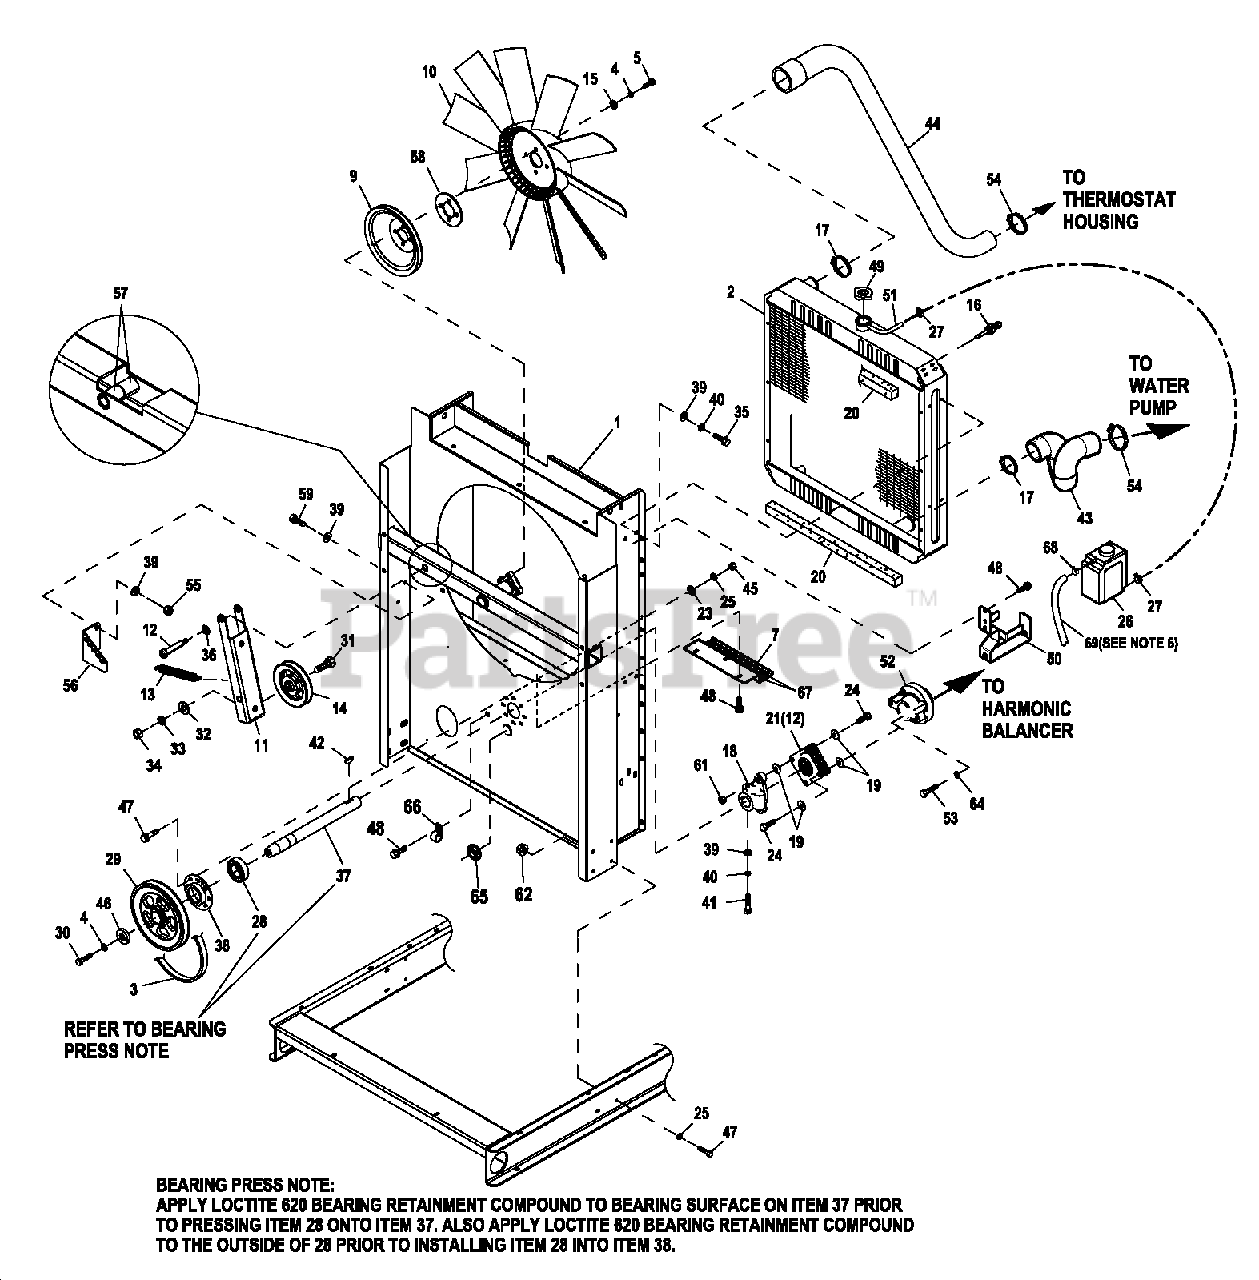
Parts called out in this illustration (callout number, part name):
1	WELDMENT RADIATOR SUPPORT C2
2	RADIATOR 598 X 568 X 19.CPL LH
3	V-BELT A51 (53INO.C)
4	WASHER LOCK M10
5	SCREW HHC M10-1.5X 30 G10.9
7	SHIELD RADIATOR C2
9	PULLEY FAN, V-GROOVE
10	FAN COOL 22" DIA 10 BLADE LH
11	ARM BELT TENSIONER
12	SHOULDER BOLT 1/2 X 2-1/4"
13	SPRING TENSION CPL
14	PULLEY V-BELT 4" FLANGED
15	WASHER FLAT 3/8-M10 ZINC
16	PROBE COOLANT LEVEL 3/8-18NPTF
17	CLAMP HOSE #28 1.32-2.25
18	HUB FLEX PLATE
19	WASHER FLEX (THIN)
20	TAPE FOAM 1 X 1 (26.75" LG)
21	DISK FLEX
23	WASHER FLAT 1/4-M6 ZINC
24	SCREW HHC 5/16-24X1.124
25	WASHER LOCK M6-1/4
26	TANK COOLANT RECOVERY
27	CLAMP HOSE BAND 1/4
28	BEARING #6205 2NSE C3 E SRI2 S
29	PULLEY 6" DIA MACHINED
30	SCREW HHC M10-1.5X30 G8.8
31	SCREW HHC 1/2-13X2" G8
32	WASHER FLAT 1/2 ZINC
33	WASHER LOCK 1/2
34	NUT HEX 1/2-13 STEEL
35	SCREW HHFC M8-1.25 X 20 W/M6
36	WASHER NYLON .50 X .87 X .06
37	SHAFT FAN DRIVE
38	RETAINER BEARING
39	WASHER FLAT 5/16-M8ZINC
40	WASHER LOCK M8-5/16
41	SCREW HHC M8-1.25X 45 C8.8
42	KEY WOODRUFF 4 X19D
43	HOSE LOWER RAD CPL C2 5.4L
44	HOSE RADIATOR UPPER C2 CPL
45	NUT HEX M 6X1.0 G8 YELCHR
46	SPACER .5X1.5X.25STL/ZINC
47	SCREW HHFC M6-1.0X 2 0 G8.8
48	SCREW THF M6-1 X 16 N WA Z/JS
49	CAP RADIATOR 13 PSI
50	BRACKET COOLANT TANK
51	HOSE 9/32 ID (60"LG)
52	COUPLING FLEX HUB MACHINED
53	SCREW HHC M12-1.5X 70 C10.9
54	CLAMP HOSE #24 B1.06-2.00
55	NUT HEX LOCK M8-1.25 NY INS
56	BRACKET TENSIONER SPRING
57	BEARING SLEEVE 1/2/X 3/4X1
58	SPACER CPL COOLING FAN 1/8"
59	SCREW HHC M8-1.25X20 C8.8
61	NUT HEX LOCK 5/16-24 NY INS
62	NUT FLANGE M6-1.0 NYLOK
64	WASHER LOCK M12
65	GROMMET 1.37 X .06 X 1.00
66	CLAMPSTL/VNL .7 5X .3 4 3Z
67	FOAM STRIP 3/4"WIDE X 3/16"THK (12"LG)
68	CLAMP HOSE BAND .50
69	HOSE 9/32 ID (27"LG)
